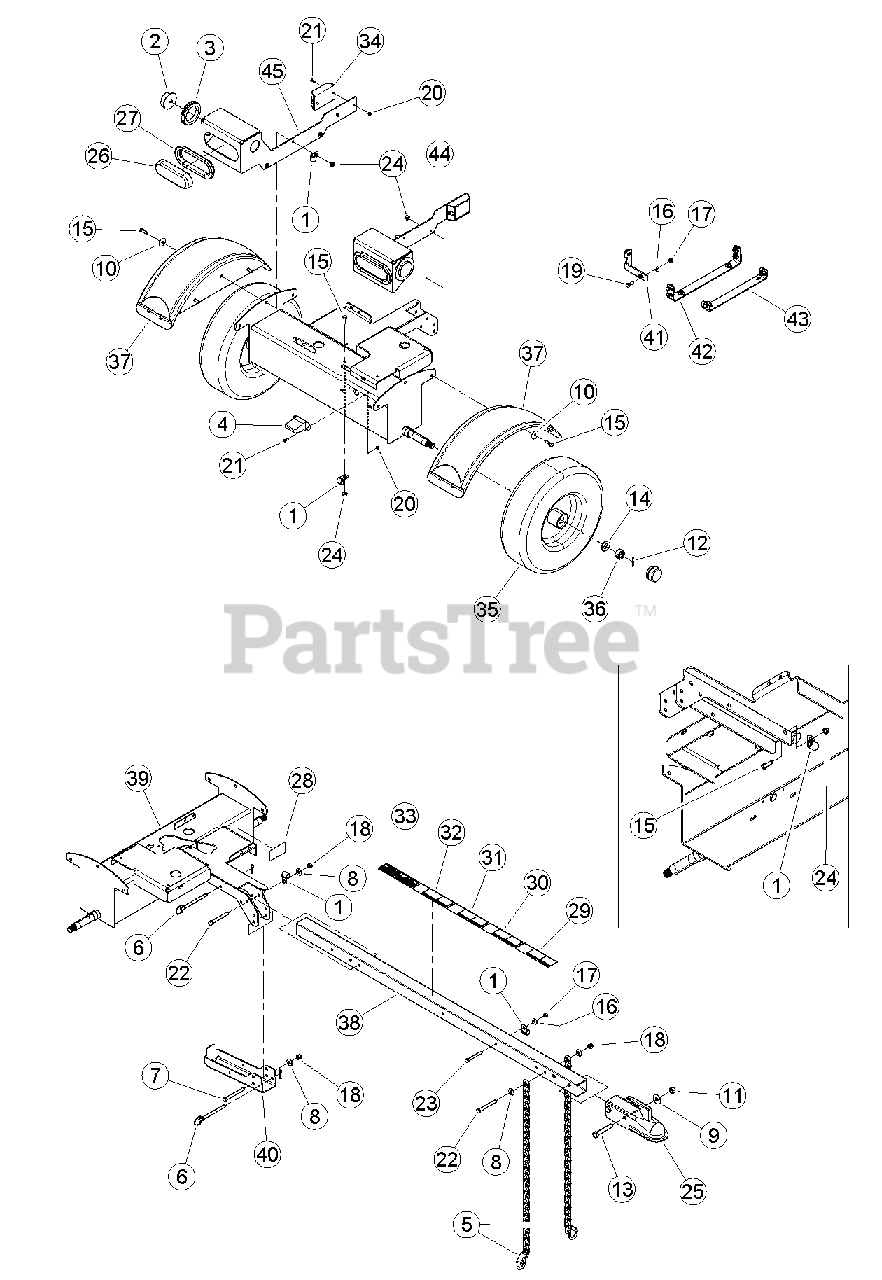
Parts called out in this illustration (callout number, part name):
1	NUT, 3/4 NF HEX SLOTTED ZP
2	CLAMP, 9/16 COATED
3	GROMMET, CLEARANCE LIGHT
4	LIGHT, LICENSE PLATE
5	CHAIN, SAFETY 5000 LB W/ LATCH
6	DECAL, ECHO BEARCAT 14.12 X 4.00
7	PIN, 3/8 HITCH
8	BOLT, 5/16-18 X 3/4 GR5 HEX HD
9	WASHER, 3/8 FLAT
10	WASHER, 5/16" FENDER ZP
11	NUT, 1/2-13 GR5 CENTERLOCK GRB
12	PIN, 5/32 X 1-1/4 COTTER PIN ZP
13	BOLT, 1/2 X 3 GR5 HEX HD ZP
14	WASHER, 3/4" SAE FLAT
15	BOLT, 5/16-18 X 1 GR5 HHCS
16	WASHER, 5/16 FLAT
17	NUT, 5/16-18 NE NYLOCK
18	NUT, 3/8-16 NE NYLOCK
19	BOLT, 5/16-18 X 7/8 HHCS GR5
20	NUT, 10/24 NYLOCK TYPE NM ZP
21	SCREW, #10-24 X 3/4" PAN HD PH ZP MCH
22	BOLT, 3/8 X 3-1/4 HEX HD GR5 ZP
23	BOLT, 5/16-18 X 2-3/4 GR5 HCPS
24	NUT, 5/16-18 NYLOCK FLANGE
25	NUT, 3/8-16 NYLOCK FLANGE
26	COUPLER, TRAILER HITCH
27	TAIL LIGHT, OVAL LED
28	GROMMET, OVAL TAIL LIGHT
29	DECAL, 4.80-8 LOAD RATING
30	DECAL, NATM COMPLIANCE
31	LIGHT, CLEARANCE/MARKER RND RED LED
32	ASSEMBLY, TIRE 4.8-8
33	KIT, LED AMBER LIGHT
34	FENDER, BLACK PLASTIC DRILLED
35	STAND, JACK
36	BRACKET, ENGINE BASE
37	BRACKET, RIGHT TAIL LIGHT
38	BRACKET, LEFT TAIL LIGHT
39	ASSEMBLY, HITCH POLE
40	DECAL, SAFETY CHAINS
41	DECAL, TRAILER ELECTRICAL
42	DECAL, CHECK WHEELS
43	DECAL, SAFE COUPLING
44	DECAL, WARNING TOWING SPEED
45	WELDMENT, SC3" TRAILER
